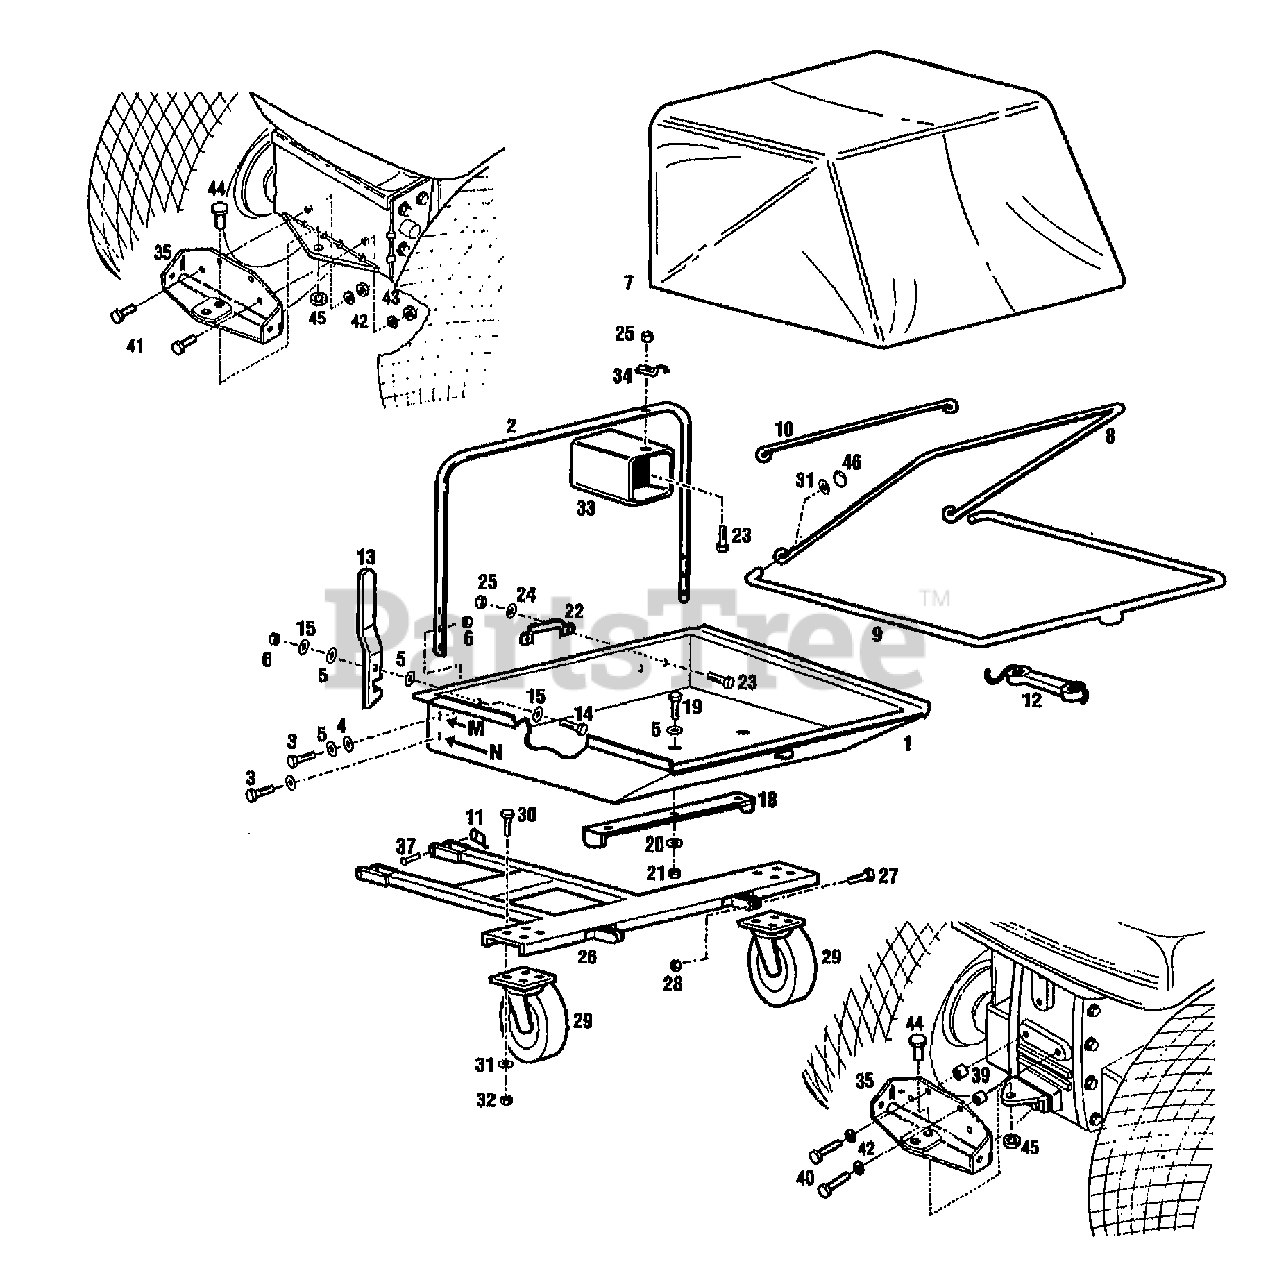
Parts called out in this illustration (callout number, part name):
2	TUBE-SUPPORT
3	SCR-HH 5/16-18X1.5 G5 ZP
4	SPACER
5	WASHER-FLAT 5/16 SAE
6	NUT-TOP/LK 5/16-18 ZP
8	ROD-SUPPORT
9	ROD-FRAME
10	ROD-STRAIGHT
11	RING-COTTER
12	STRAP
13	HANDLE-LATCH
14	SCR-HH 5/16-18X1.0 G5 ZP
15	WASHER
18	BRACKET-U
19	SCR-5/16-18X1.00
20	WASHER-LK .312 ZP
21	NUT-HEX 5/16-18 ZP
22	HANDLE-LIFT
23	SCR 1/4-20X.5 TRUSS HD
24	WASHER-LK .25 ZP
25	NUT-HEX 1/4-20 ZP
27	SCR-HH 1/2-13X1.25 G5 ZP
28	NUT-TOP LOCK 1/2-13 ZP
30	SCR-HH 3/8-16X1.0 G5 ZP
31	WASHER-FLAT 3/8 SAE
32	NUT-LOCK 3/8-16
33	SLEEVE
34	ASSM-SLEEVE CLAMP
35	PLATE-MOUNTING GRASSBAG
37	PIN-CLEVIS .5X1.25
39	SPACER-.75X.531X.89
40	SCR-HH 1/2-13X1.75 G5 ZP
41	SCR-HH 1/2-13X1.0 G5 ZP
42	WASHER-LK .5
43	NUT-HEX JAM 1/2-13
45	NUT-H/LK 3/4-10
46	RING-CIRCLE COTTER
